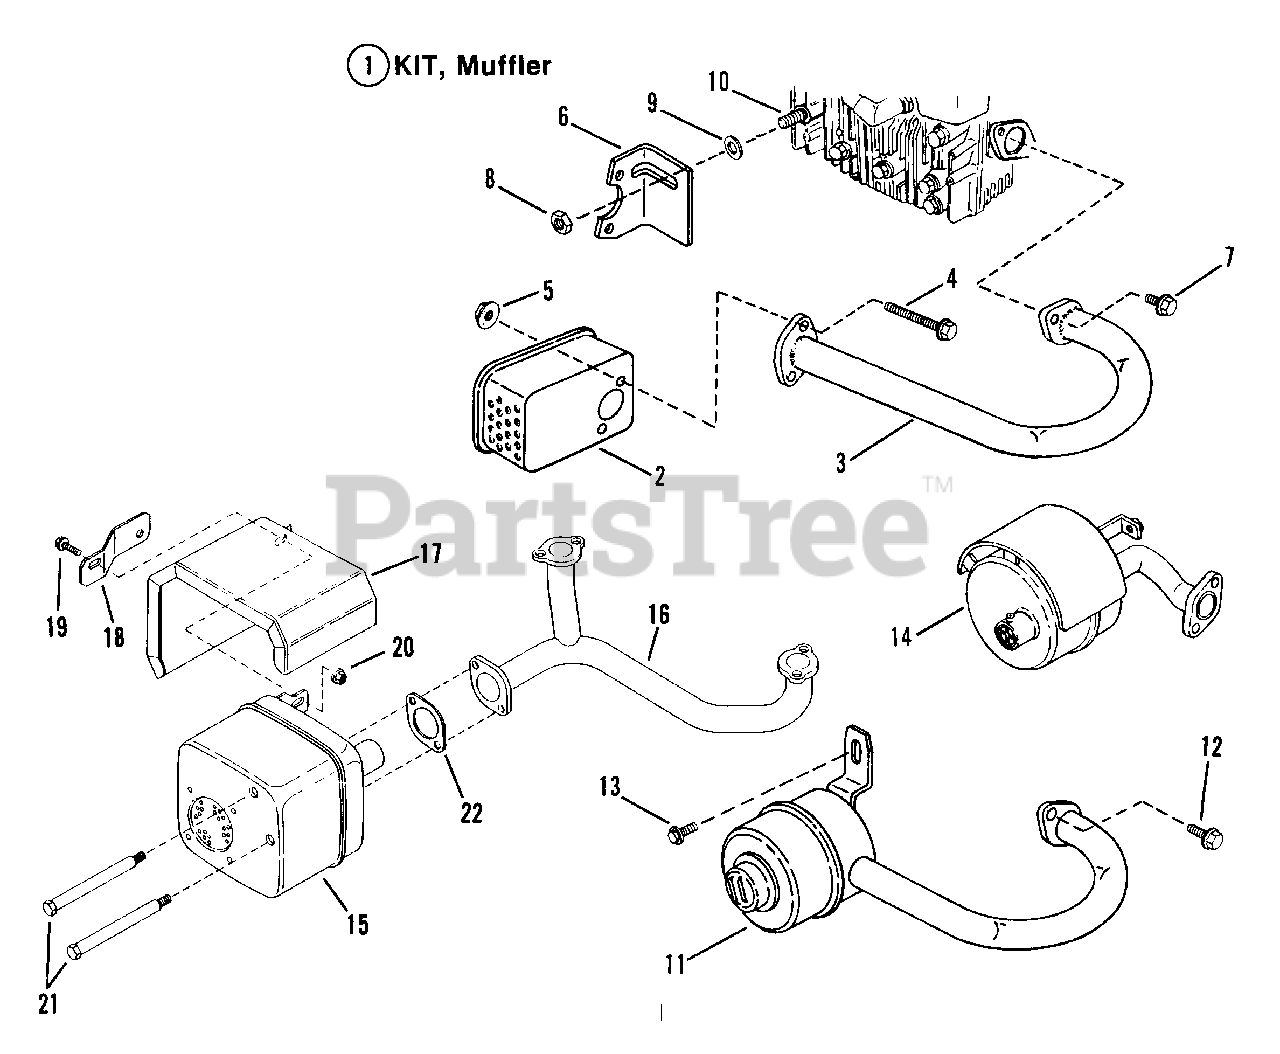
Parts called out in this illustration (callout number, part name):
1	KIT, Muffler
2	MUFFLER
3	TUBE, Exhaust
4	SCREW, 5/16-18 x 3" Hex Head Cap
5	NUT, 5/16-18 Hex Flange Lock
6	BRACKET, Muffler
7	SCREW, 1/4-20 x 5/8" Hex Head Cap
8	NUT, 5/16-18 Hex
9	WASHER, 21/64 Flat
10	STUD, Cylinder Head
11	MUFFLER
12	SCREW, 5/16-18 x 3/4" Hex Head Cap
13	SCREW, 1/4-20 x 3/4" Hex Head Cap
14	MUFFLER
15	MUFFLER
16	MANIFOLD, Exhaust
17	SHIELD, Muffler
18	BRACE, Muffler
19	BOLT, 1/4-20 x 5/8" Hex Flange Lock
20	NUT, 1/4-20 Hex Flange Lock
21	BOLT, 5/16-18 (1/2") x 4" Shoulder
22	GASKET, Exhaust
